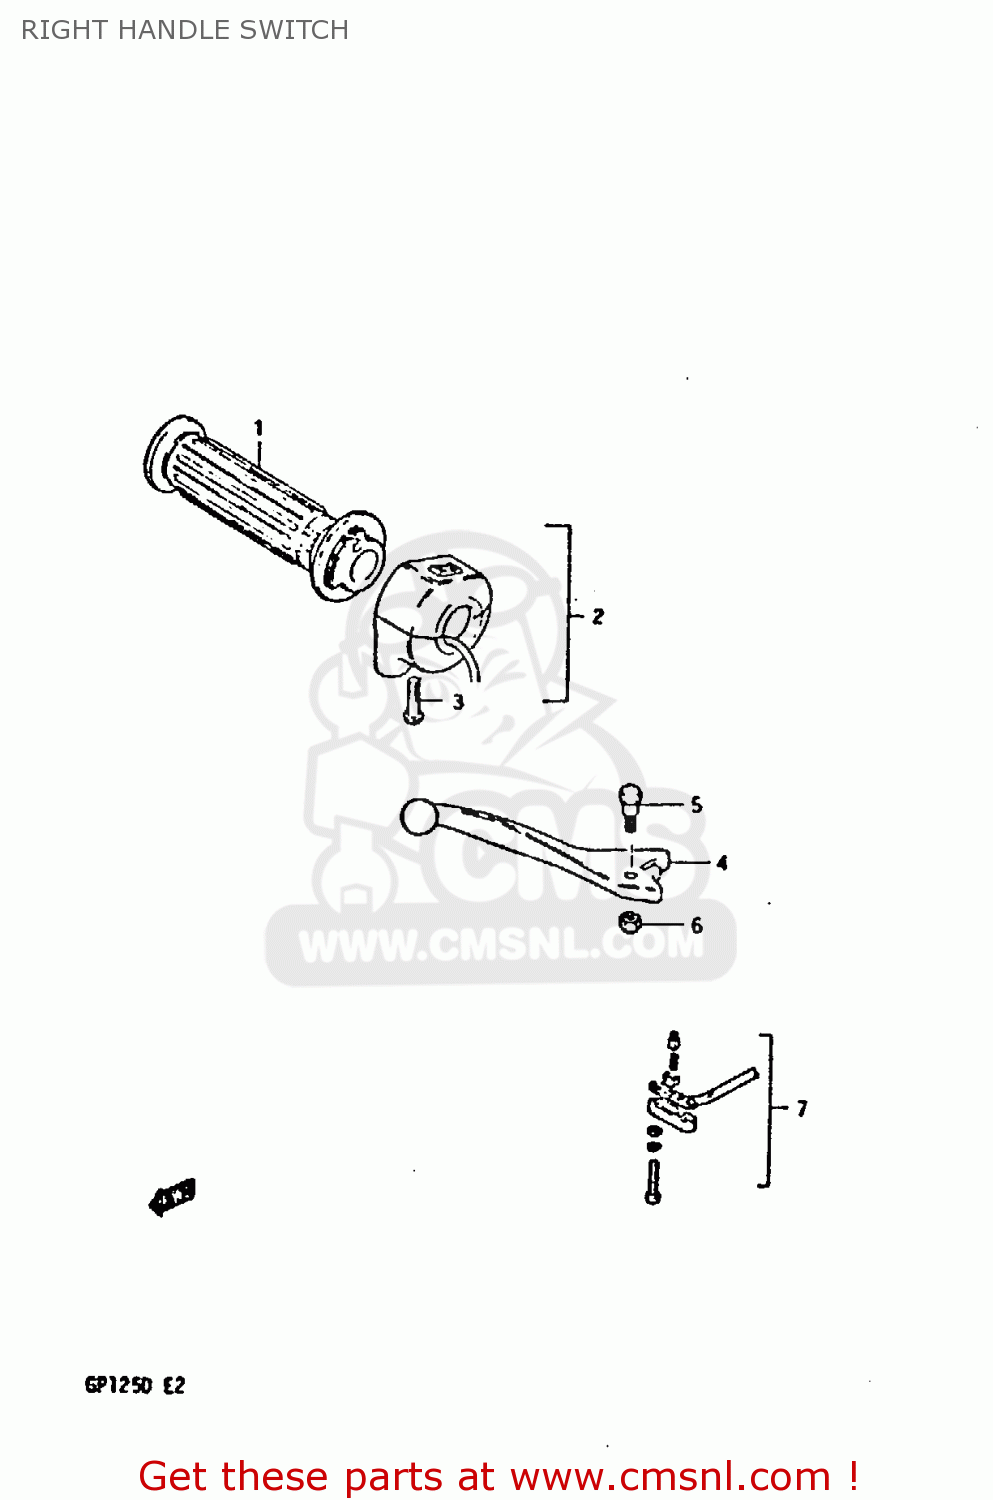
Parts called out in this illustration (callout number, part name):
1	GRIP,THROTTLE
2	CASE ASSEMBLY,THROTTLE
3	SCREW
4	LEVER,BRAKE
5	BOLT
6	NUT 6MM
